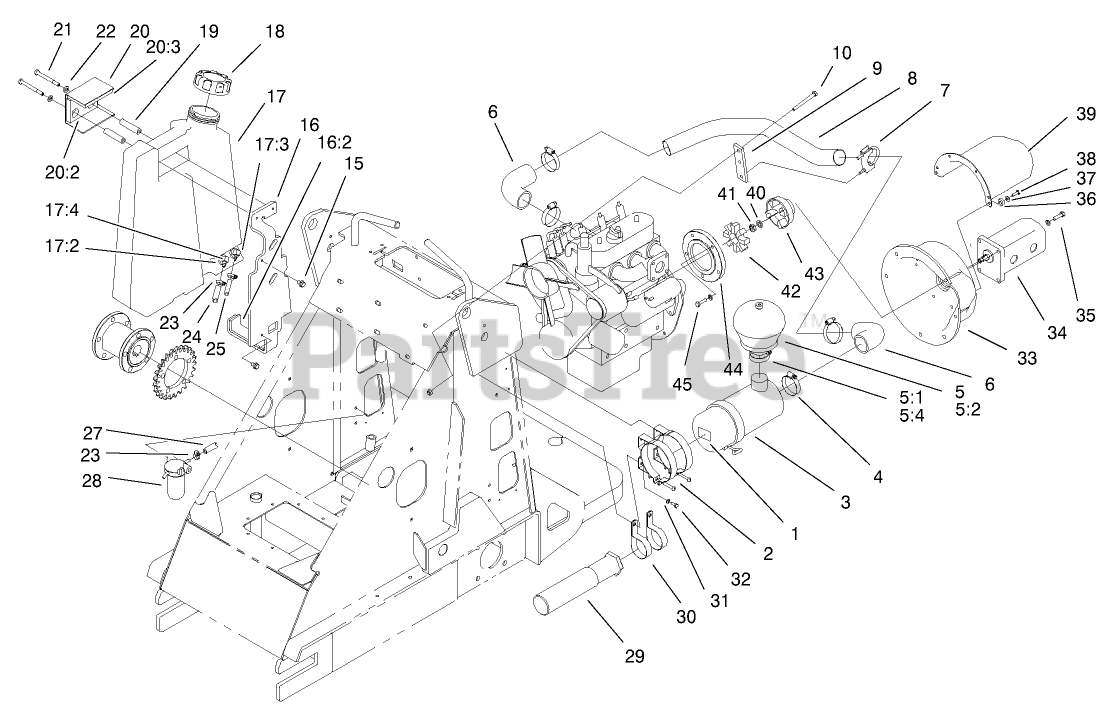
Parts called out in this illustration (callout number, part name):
1	DECAL-FLUID, STARTING
2	MTG BAND ASM
3	AIR CLEANER ASM
4	CLAMP-HOSE
5	PRE CLEANER
5:1	COVER ASM
5:2	BOWL-CLEAR
5:4	CLAMP
6	HOSE-AIR FILTER
7	U-BOLT
8	TUBE-AIR FILTER
8:1	SEAL KIT
9	MOUNT-TUBE
10	SCREW-HH
15	SCREW-FLANGE
16	MOUNT ASM
16:2	PAD-FOAM
17	FUEL TANK ASM, DIESEL
17:2	BUSHING
17:3	FITTING-90 DEG
17:4	FITTING-90 DEGREE
18	DIESEL FUEL CAP ASM
19	SPACER
20	PLATE ASM
20:2	PAD-FOAM
20:3	PAD-FOAM
21	SCREW-HH
22	WASHER-PLAIN
23	CLAMP-WORM
24	HOSE-FUEL
25	HOSE-FUEL
27	HOSE
28	FUEL FILTER ASM
29	TUBE-MANUAL
30	CLAMP-R
31	WASHER-LOCK
32	SCREW-HH
33	MOUNT-PUMP, DIESEL
34	PUMP-GEAR, TANDEM
35	SCREW-CAP, HH
36	WASHER-RUBBER
37	WASHER-FLAT
38	SCREW
39	Guard-Pump
40	WASHER-LOCK
41	NUT-JAM
42	HUB-PUMP
43	COUPLING
44	COUPLER-PUMP, DIESEL
